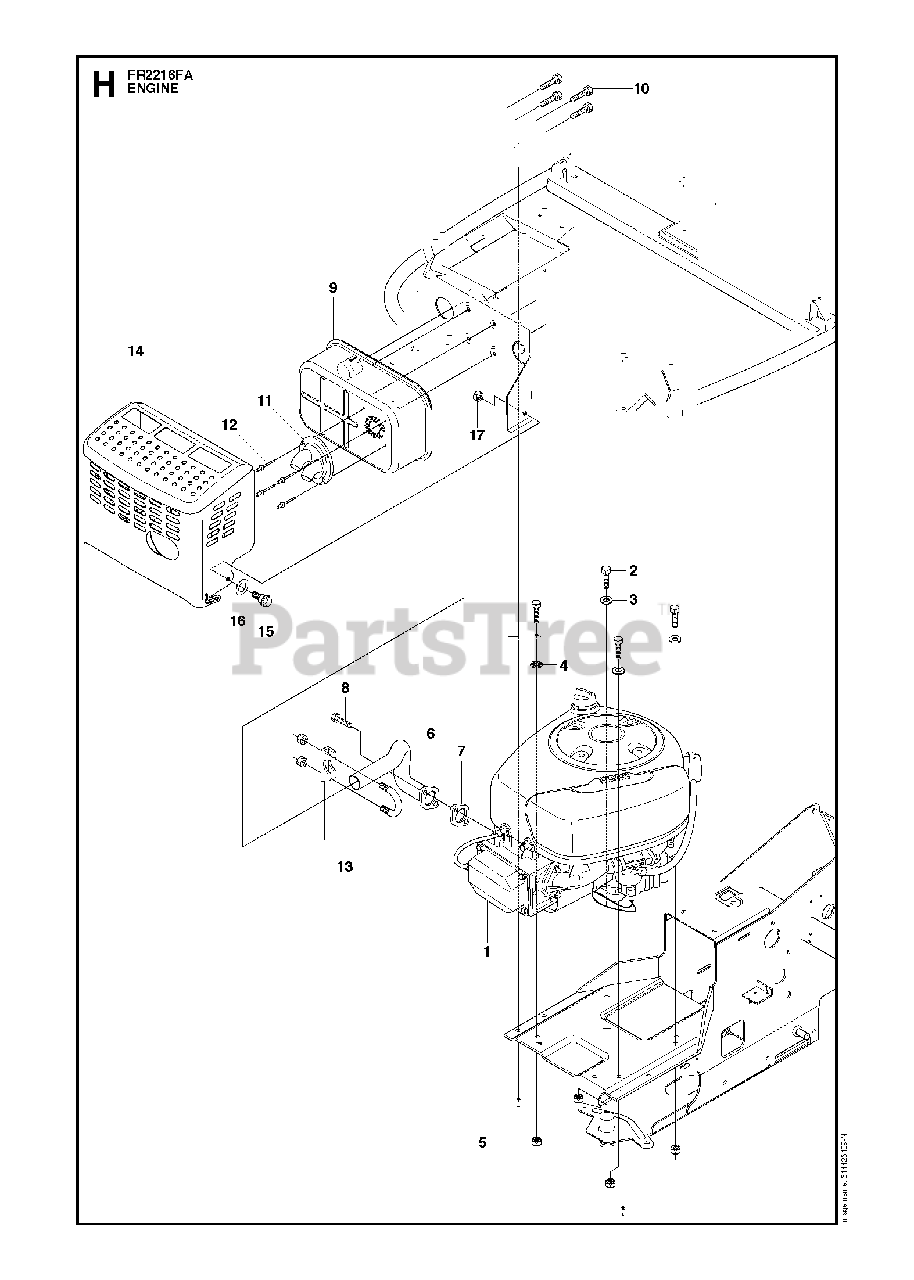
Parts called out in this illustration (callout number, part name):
3	WASHER BRB 8.4X17
5	LOCKNUT M8
9	MUFFLER
16	SPRINGWASHER
17	LOCKNUT M8
